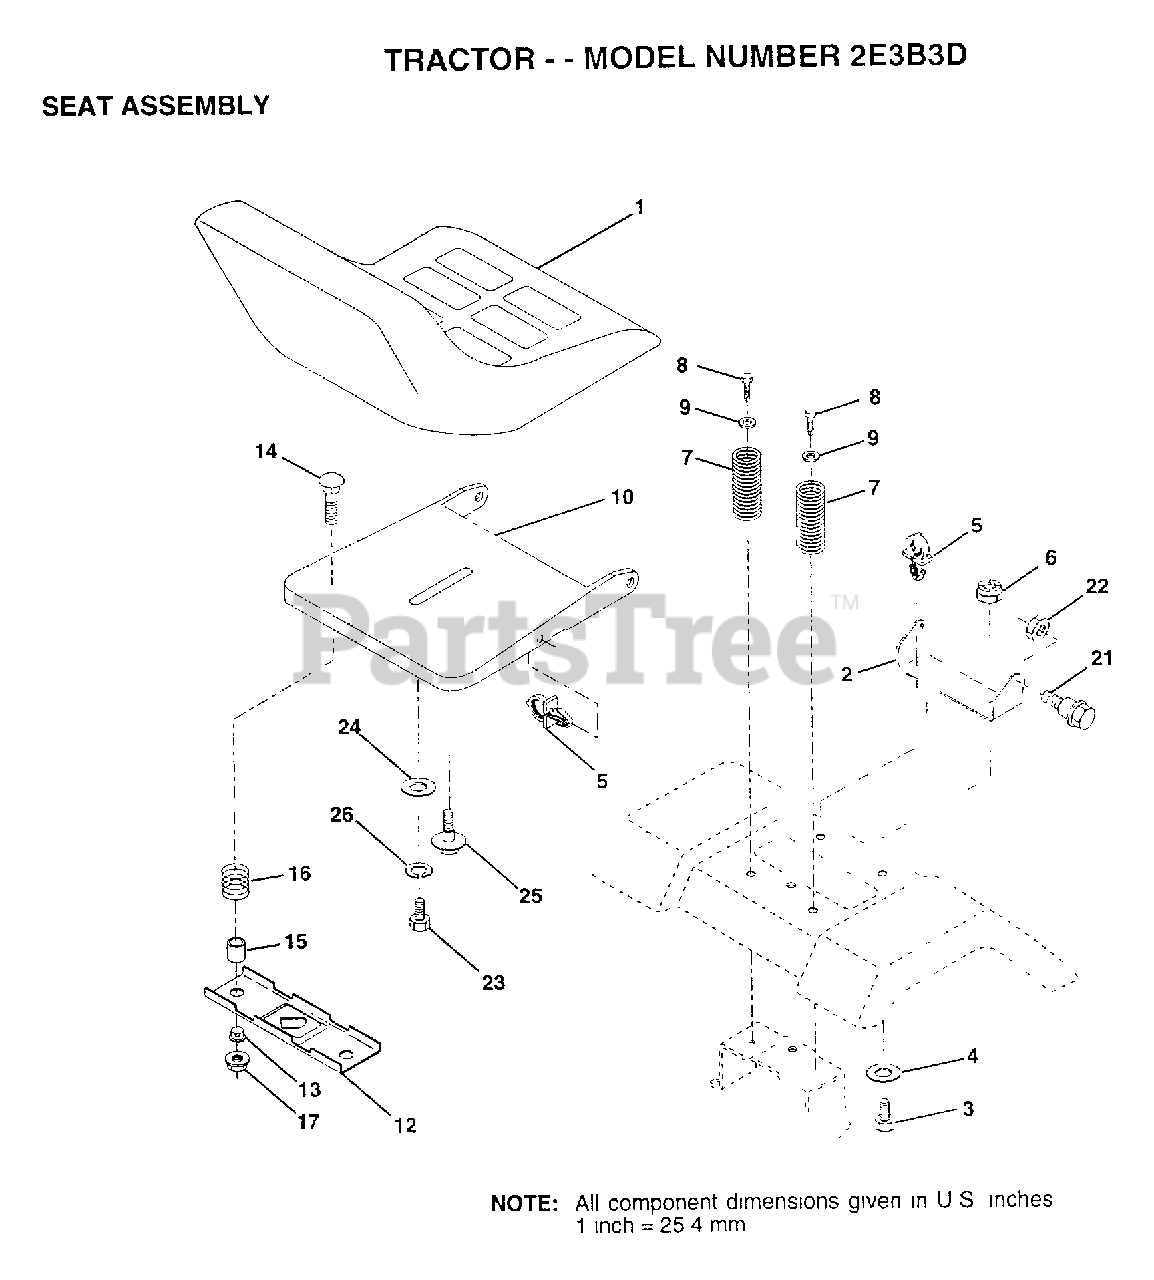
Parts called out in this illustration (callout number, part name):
2	BRACKET PVT SEAT
3	BOLT
4	WASHER PM
5	CLIP.PUSH-IN.HING
6	NUT
7	SPRING COMPRESSIO
8	SCREW GTV
9	WASHER
12	BRKT SWITCH
13	BUSHING
14	BOLT, CARRIAGE
15	SPLIT SPACER
16	SPRING
21	"BOLT,SHOULDER"
22	NUT
23	BOLT
24	WASHER
25	"BOLT,SHOULDER"
26	LOCKWASHER
